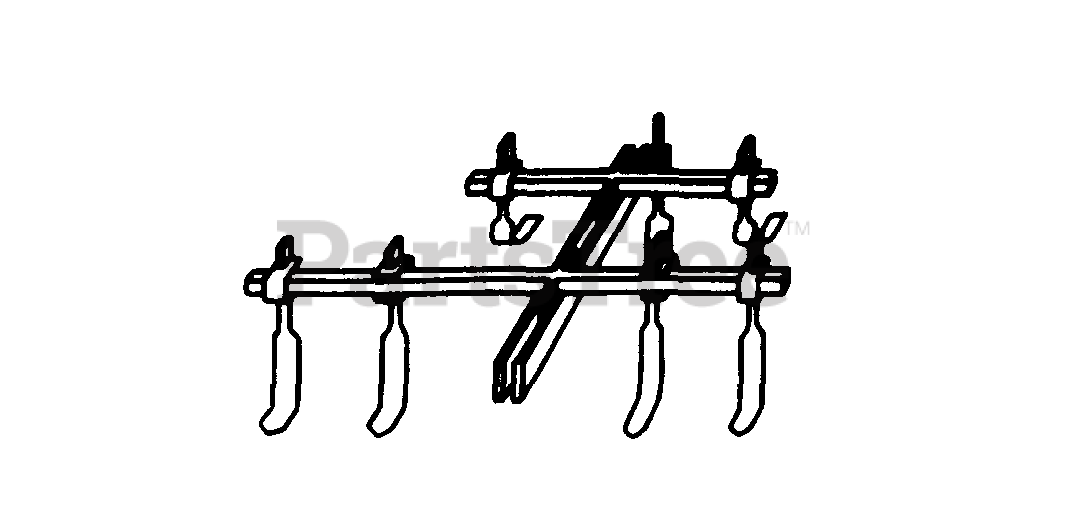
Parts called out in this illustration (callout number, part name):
2	(NLA) GAGE-SHOE
3	(NLA) SHANK
4	(NLA) CLAMP, Shank
5	(NLA) DRAW-BAR
6	(NLA) CROSS-BAR
7	SCREW, 1/2-13 x 1-1/2" H H C
8	WASHER, 1/2" Split Lock
9	NUT, 1/2-13 Hex
10	BOLT, 1/2-13 x 2" Sq Nk, Gr 5
11	NUT, 1/2-13 Hex Flange lock
12	(NLA) BOLT, 3/8-16 x 1-1/4" Plow
13	WASHER, 3/8" Split Lock
14	NUT, 3/8-16 Hex
